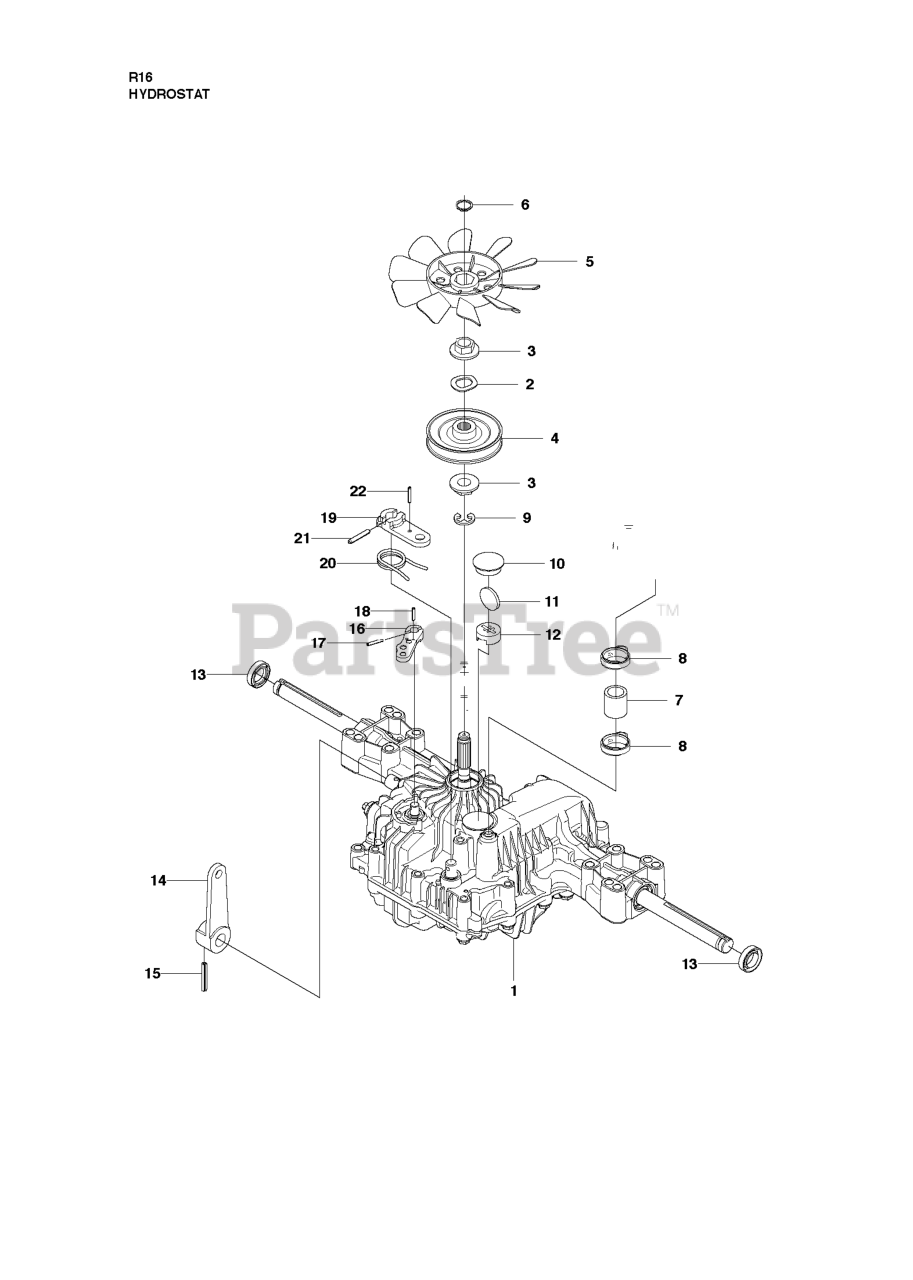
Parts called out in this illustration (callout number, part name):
1	HYDROSTAT 7A646024070
5	FAN.BLACK.1A646083070
6	RETAINING RING **
8	CLAMP
13	RP SEAL.19, 19216334280
14	CONTROL LEVER
20	RETURN SPRING
